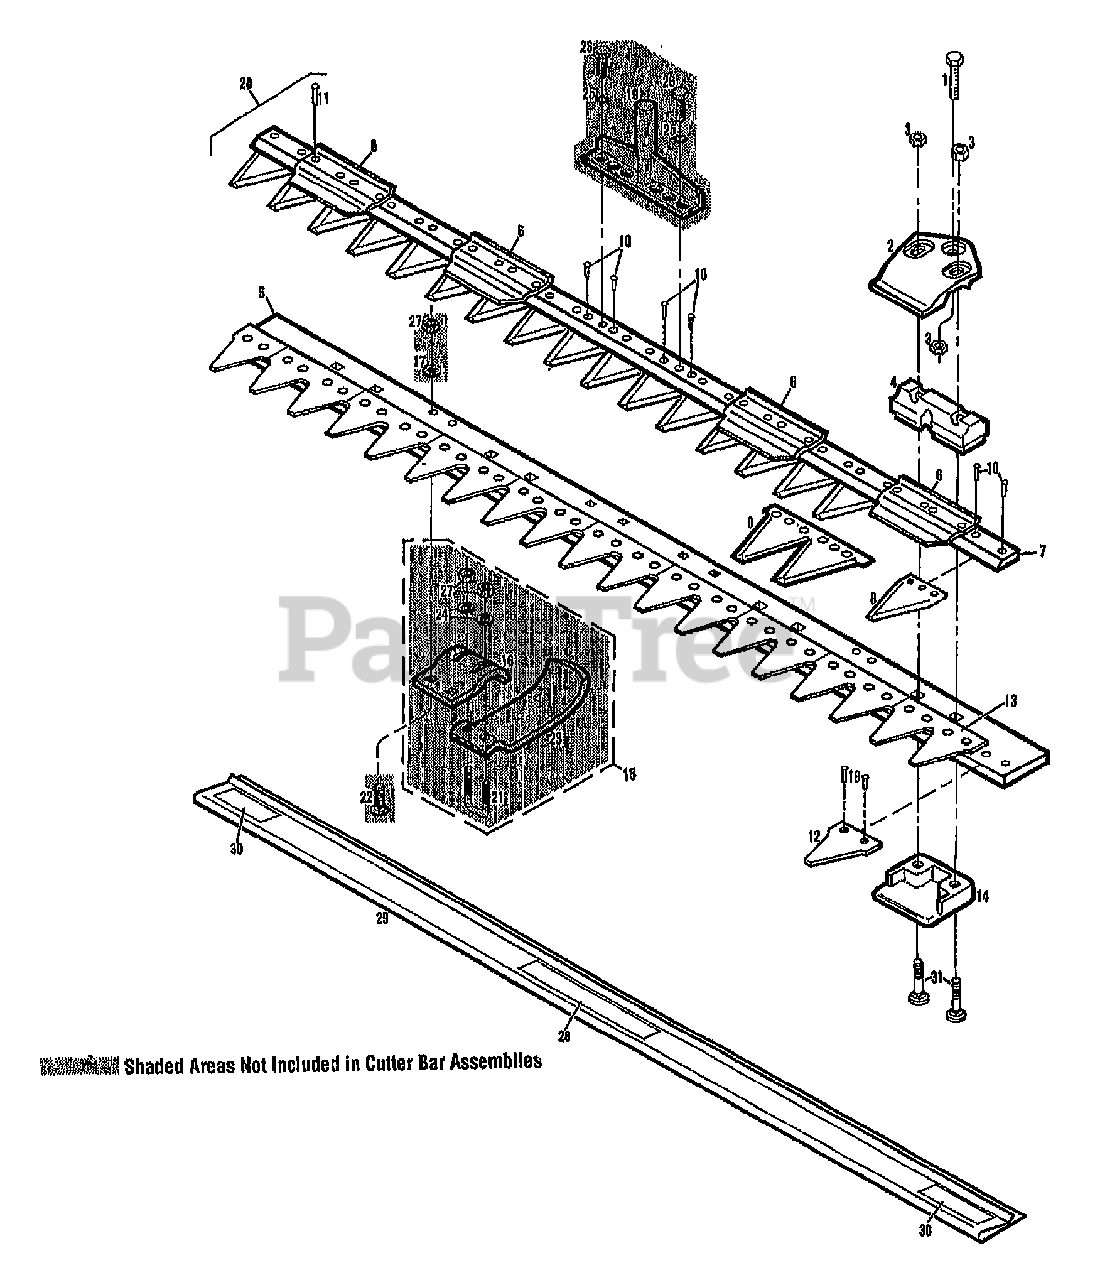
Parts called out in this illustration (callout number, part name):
1	SCR-HHC M8-1.25X30
2	CLIP-HOLD DOWN
3	NUT-H/LK M8
4	GUIDE-KNIFE
5	KNIFE-BACK BAR 34"
5	BAR-BACK 38"
5	BAR-BACK 42"
6	PLATE-WEAR
7	BAR-KNIFE 34"
7	BAR-KNIFE 38"
7	BAR-KNIFE 42"
8	KNIFE SECTION SINGLE
9	KNIFE SECTION (DOUBLE) 34"
9	KNIFE SECTION (DOUBLE) 38"
9	KNIFE SECTION (DOUBLE) 42"
10	KIT-RIVET 5X17 12 PKG
11	KIT-RIVET 5X20 12 PKG
12	PLATE-LEDGER SINGLE
13	PLATE-LEDGER DOUBLE
15	ASSM-SKID 2PC SET W/HDW (INCL. 16, 21-24, & 27)
16	SHOE-SPUR HOLDER PNT
17	WASHER-FLAT M8
18	KIT-RIVET/SEC 6X20=12 PER
19	KIT-KNIFE HEAD & PITMAN
20	ASSM-34" BLADE T/B SICKLEBAR (INCL. 6-11)
20	ASSM-38" KNIFE T/B SICKLEBAR (INCL. 6-11)
20	ASSM-42" KNIFE T/B SICKLEBAR (INCL. 6-11)
21	BOLT-U 5/16"-18
22	SCR-CARR 5/16-18X1.25 G2ZP
23	SHOE-PNT
24	WASHER-FLAT 5/16 SAE
25	WASHER-LK .312 INT TOOTH
26	SCR-HH M8
27	NUT-H/LK 5/16-18
28	DECAL-DANGER
29	GUARD-BLADE 34"
29	GUARD-BLADE 38"
29	GUARD-BLADE 42"
30	DECAL-ESM
31	SCR-HH M8X45
32	KIT-BLADE MAINT T/B SKLBR
